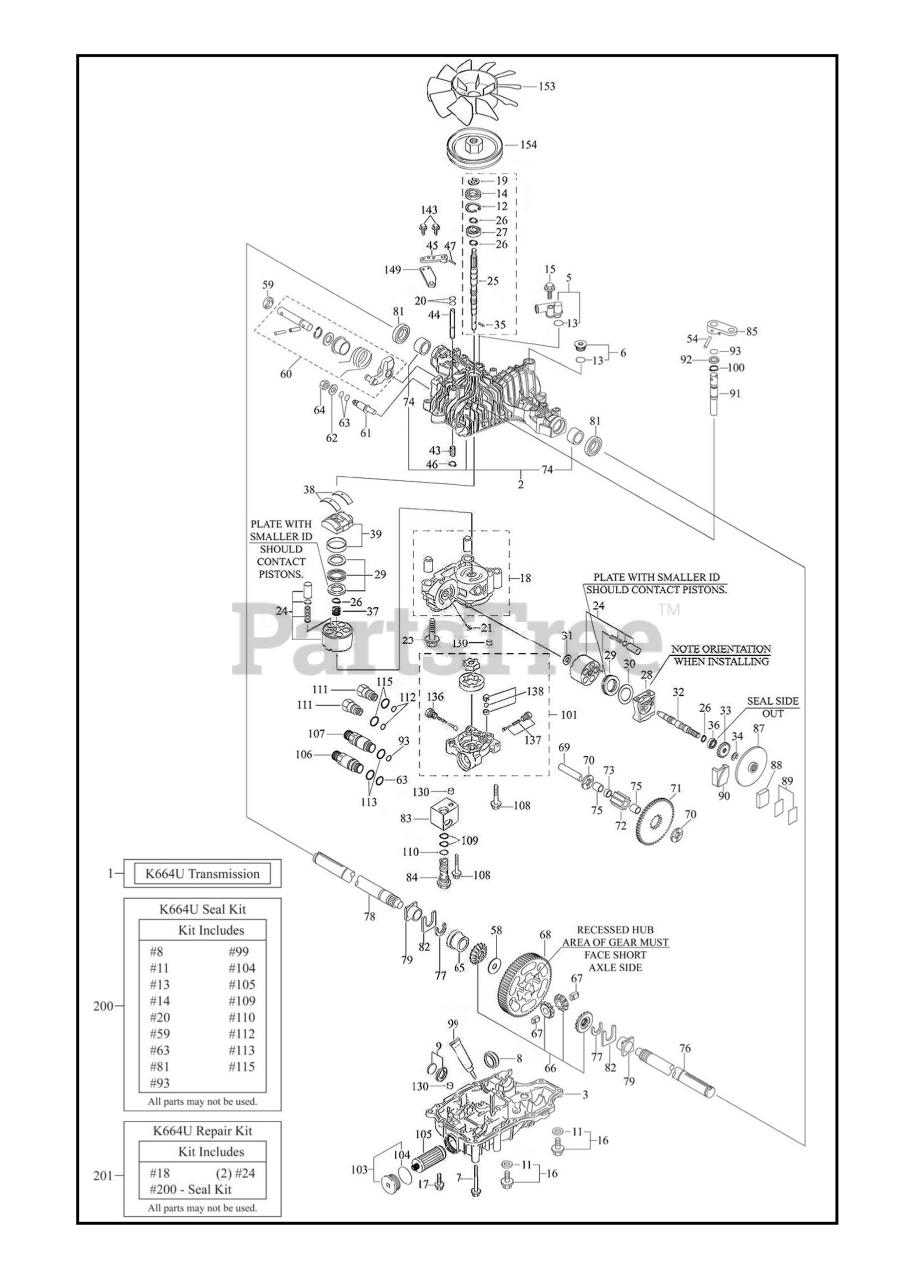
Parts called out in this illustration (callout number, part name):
7	"SCREW, CAP 8 75"
14	SEAL (24421153507)
26	SNAP RING S15
37	PUMP SPRING
59	SEALING
60	CONTROL SHAFT COMPLETE
